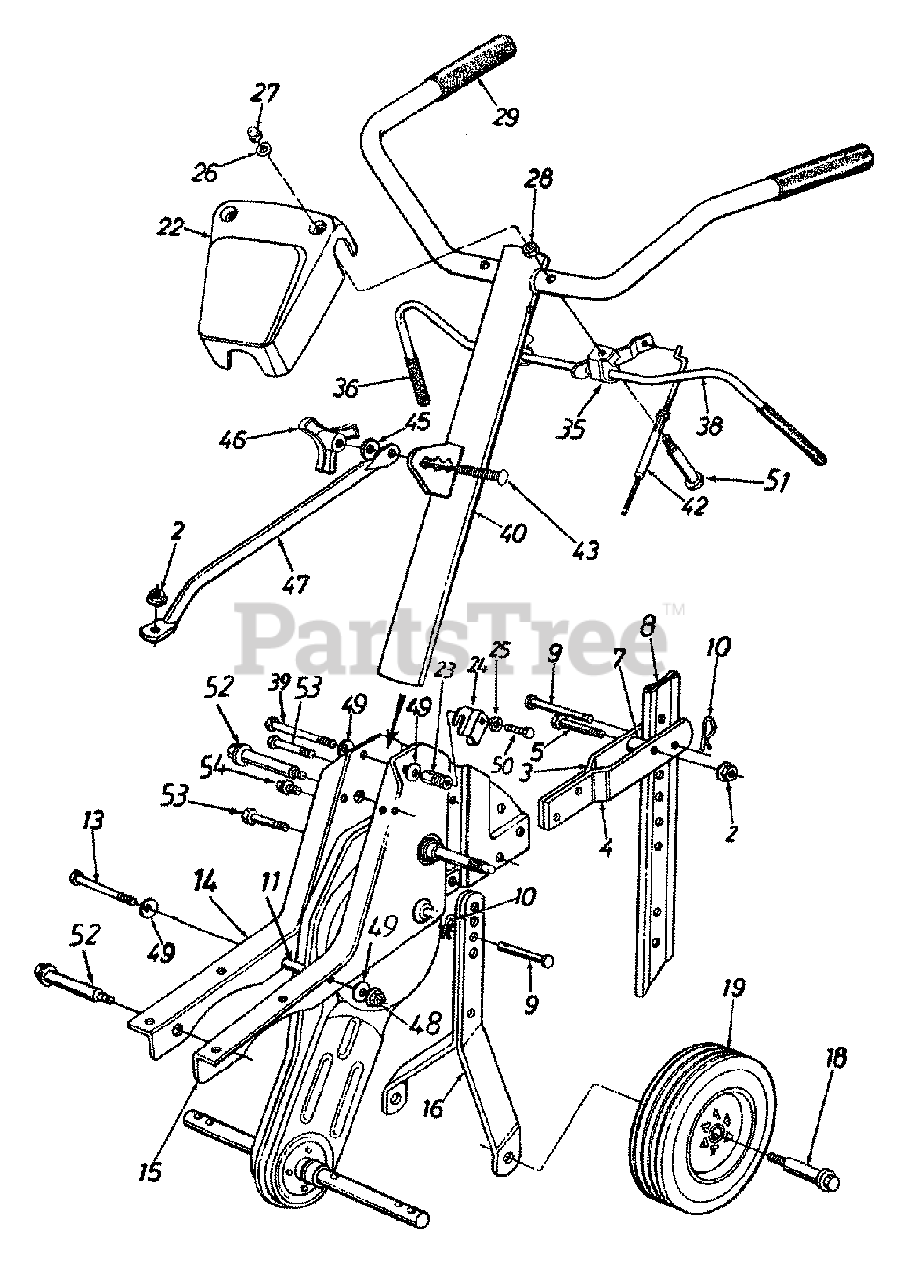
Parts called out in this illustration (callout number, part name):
2	Hex Flange L-Nut 5/16-18 Thd. (Gr. 5)
4	Tail Piece Brkt. (L.H.)
5	Hex Bolt 5/16-18 x 1.5" Lg.
7	Spacer .32" I.D. x .75" O.D.
8	Depth Bar
9	Clevis Pin .375" I.D. x 1.62" Lg.
10	Internal Cotter Pin
11	Spacer .326" I.D. x .47" O.D.
13	Hex Bolt 5/16-18 x 2.75" Lg.
15	Frame - L.H.
18	Shld. Bolt .498" Dia. x 1.45" Lg.
19	Wheel Ass'y.
22	Handle Cover
23	Spec. Hex Nut
25	L-Wash. 5/16" I.D.
26	Fl-Wash. .266" I.D. x .625" O.D.
27	Hex L-Stop Nut 1/4-28 Thd.
28	Hex Nut 1/4-20 Thd.
35	Clutch Handle Holder
36	Grip - Clutch
39	Hex Bolt 5/16-18 x 3" Lg.
40	Longhorn Handle Ass'y.
42	Clutch Control Cable
43	Carr. Bolt 5/16-18 x 1" Lg. (Special)
47	Engine Tubing Brace
48	Hex L-Nut 5/16-18 Thd.
49	Bell-Wash. .345" I.D. x .88" O.D.
50	Hex Bolt 5/16-18 x .75" Lg. (Gr. 5)
51	Hex Bolt 1/4-20 x 2.25" Lg.
52	Shld. Bolt
53	Hex Wash. Hd. TT-Tap Scr. 5/16-18 x .62" Lg.
54	Hex Wash. Hd. TT-Tap Scr. 5/16-18 x 1" Lg.
